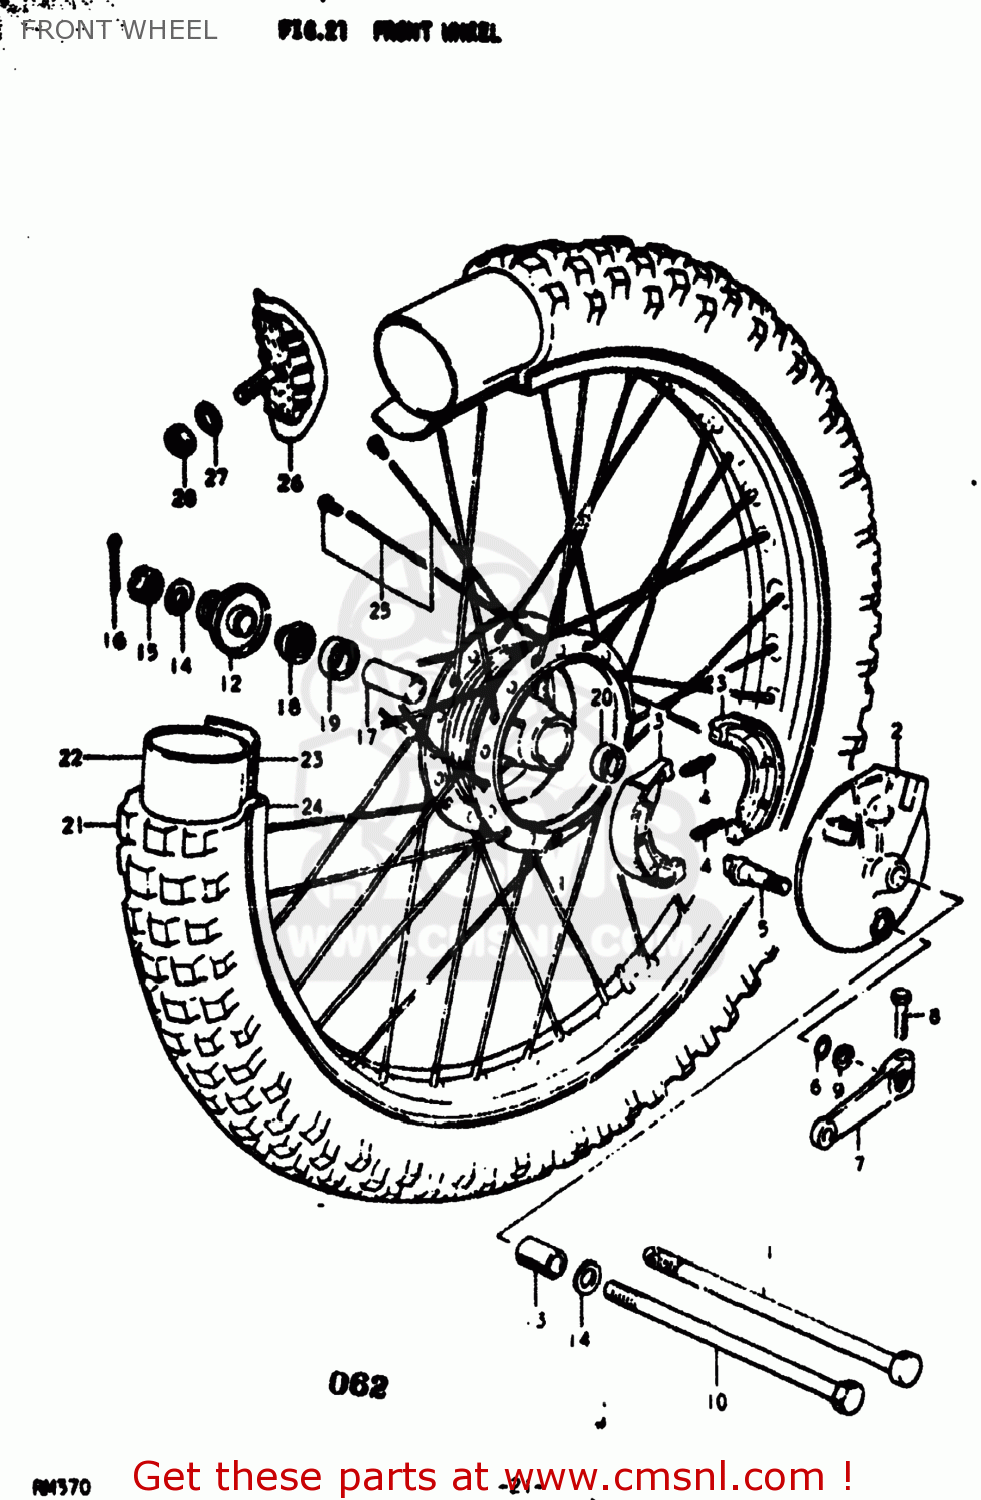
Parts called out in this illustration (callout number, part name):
1	HUB,FRONT
2	PANEL,FRONT HUB
3	SHOE,BRAKE
4	SPRING(L:34)
5	CAM,FR BRAKE
6	O RING(D:2.5,ID:11.4)
7	LEVER,FRONT BRAKE CAM
8	BOLT
9	WASHER(12.5X20X1)
10	AXLE,FRONT
11	AXLE,REAR
12	SPACER,FRONT AXLE,RIGHT
13	SPACER
14	WASHER
15	NUT, REAR AXLE
16	COTTER PIN
17	SPACER,FRONT HUB BEARING
18	OIL SEAL(17X38X5)
19	BEARING
20	BEARING, RH
21	TIRE,FRONT
22	TUBE
23	PROTECTOR,WHEEL,INNER
24	RIM,FRONT WHEEL
25	SPOKE SET
26	STOPPER,BEAD
27	WASHER 6MM
28	NUT
